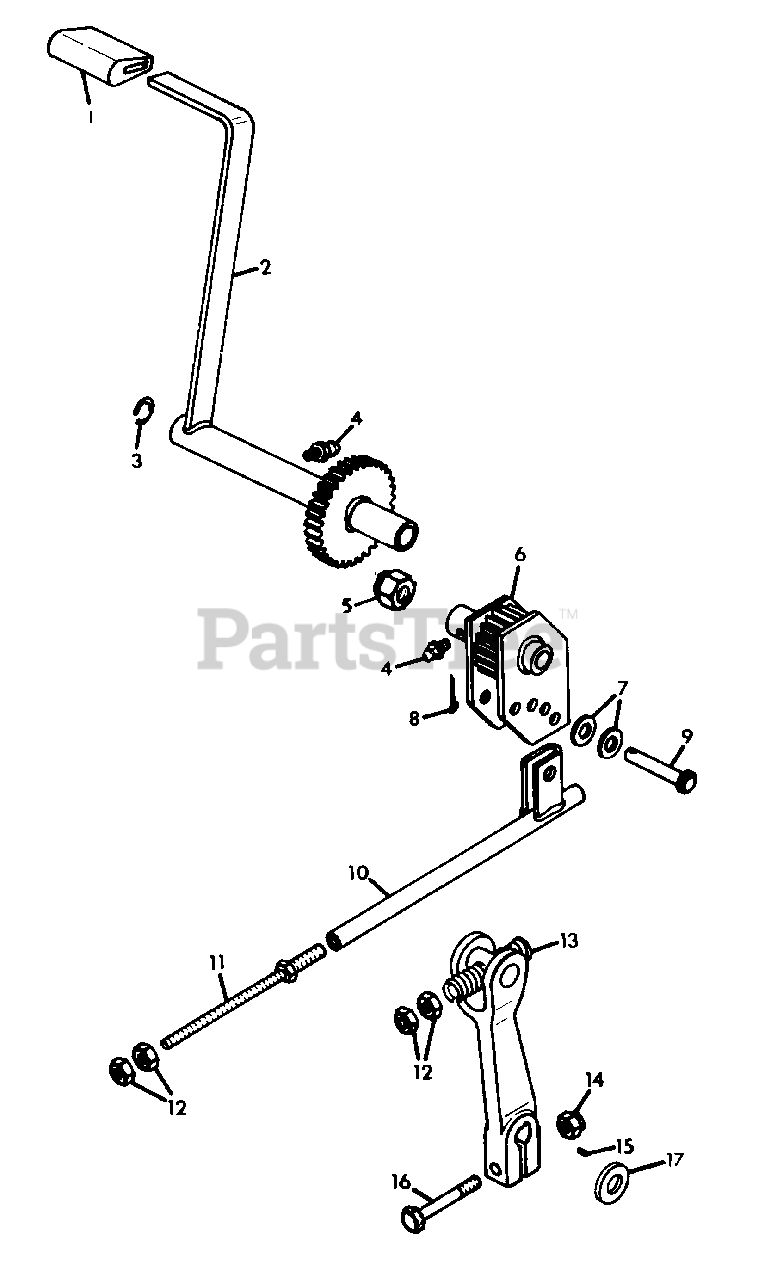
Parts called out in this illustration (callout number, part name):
1	GRIP, HANDLE
2	LEVER, FWD-REV
3	RING, RETAINING .750 SHAFT
4	FITTING, LUB 1/4-28
5	NUT, LOCK 5/8-11
6	WELDMENT, ARM FWD-REV
7	WASHER, FLAT .406X.812X.065
8	PIN, COTTER .09X.625
9	PIN, CLEVIS .375X1.531
10	WELDMENT, FWD-REV ROD
11	ROD, CONTROL EXTENSION
12	NUT, JAM 3/8-16
13	LEVER, CONTROL
14	NUT, LOCK 5/16-18
15	KEY, WOODRUFF .125X.625 HARD
16	BOLT, HEX 5/16-18X2.00
17	WASHER, FLAT .812X1.496X.134
